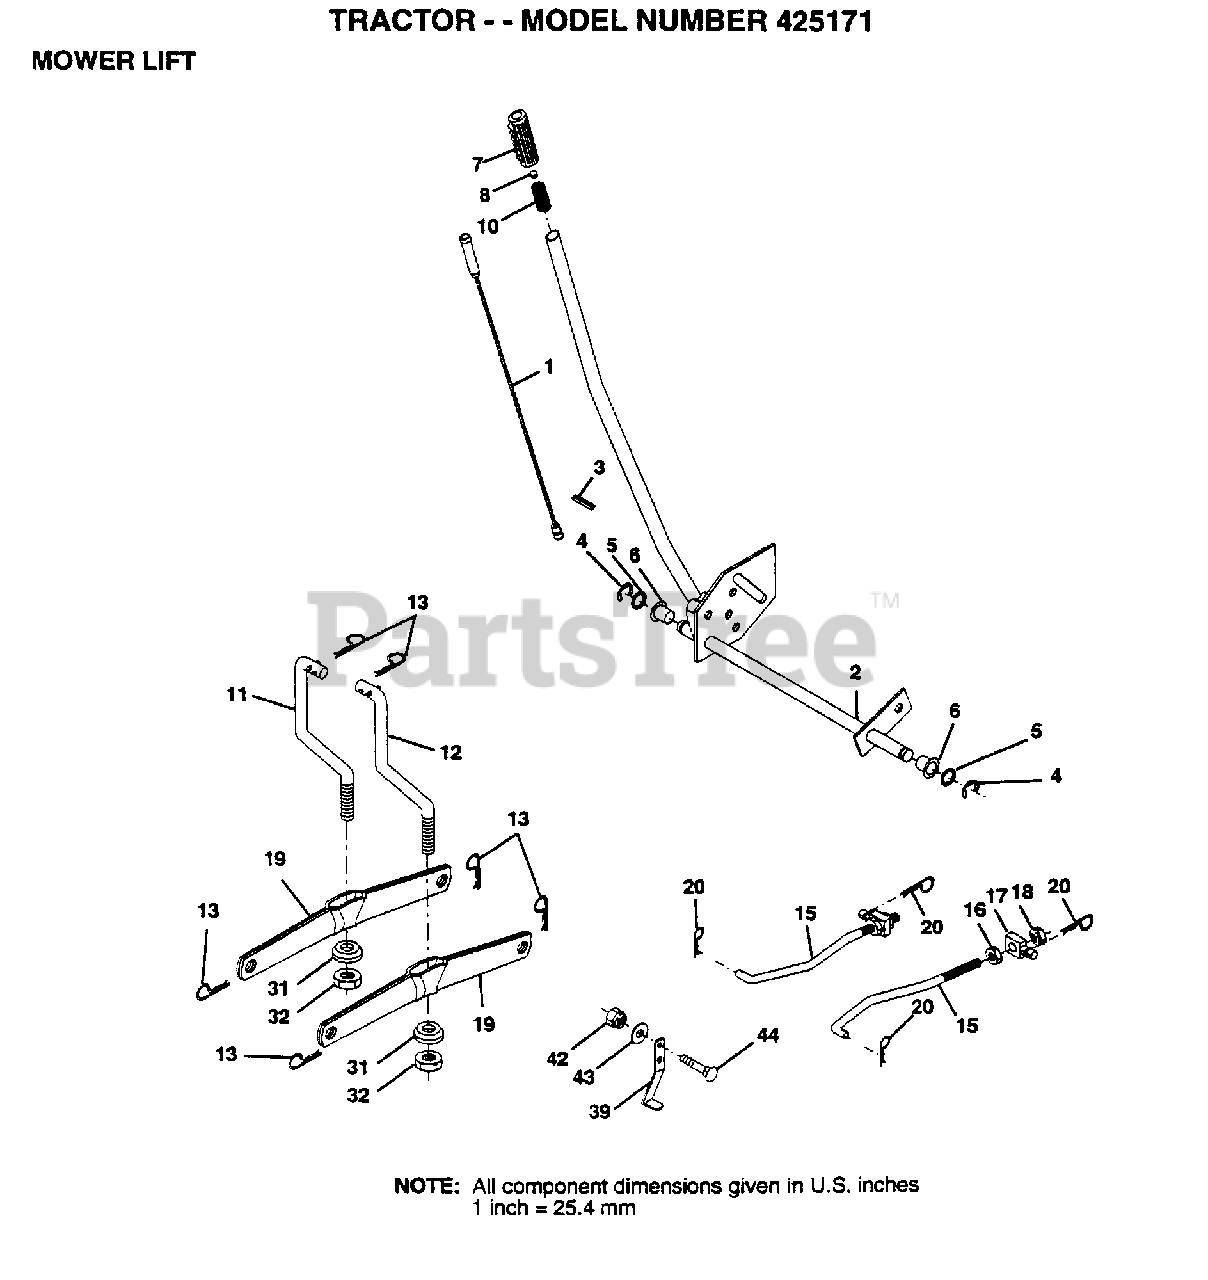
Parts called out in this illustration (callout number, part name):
1	WIRE ASM
2	SHAFT.ASM.LIFT LH
3	PIN GROOVE
5	WASHER
6	NYLON BEARING
7	GRIP
15	LINK.FRONT
16	NUT
17	TRUNION
18	NUT.LK.W/WSH.1/2.
19	ARM SUSP REAR
20	RETAINER.SPRING
31	BEARING PVT LH
32	NUT.CROWNLOCK.3/8
39	STOP.OVER.CENTER
42	NUT
43	WASHER GT
44	BOLT
